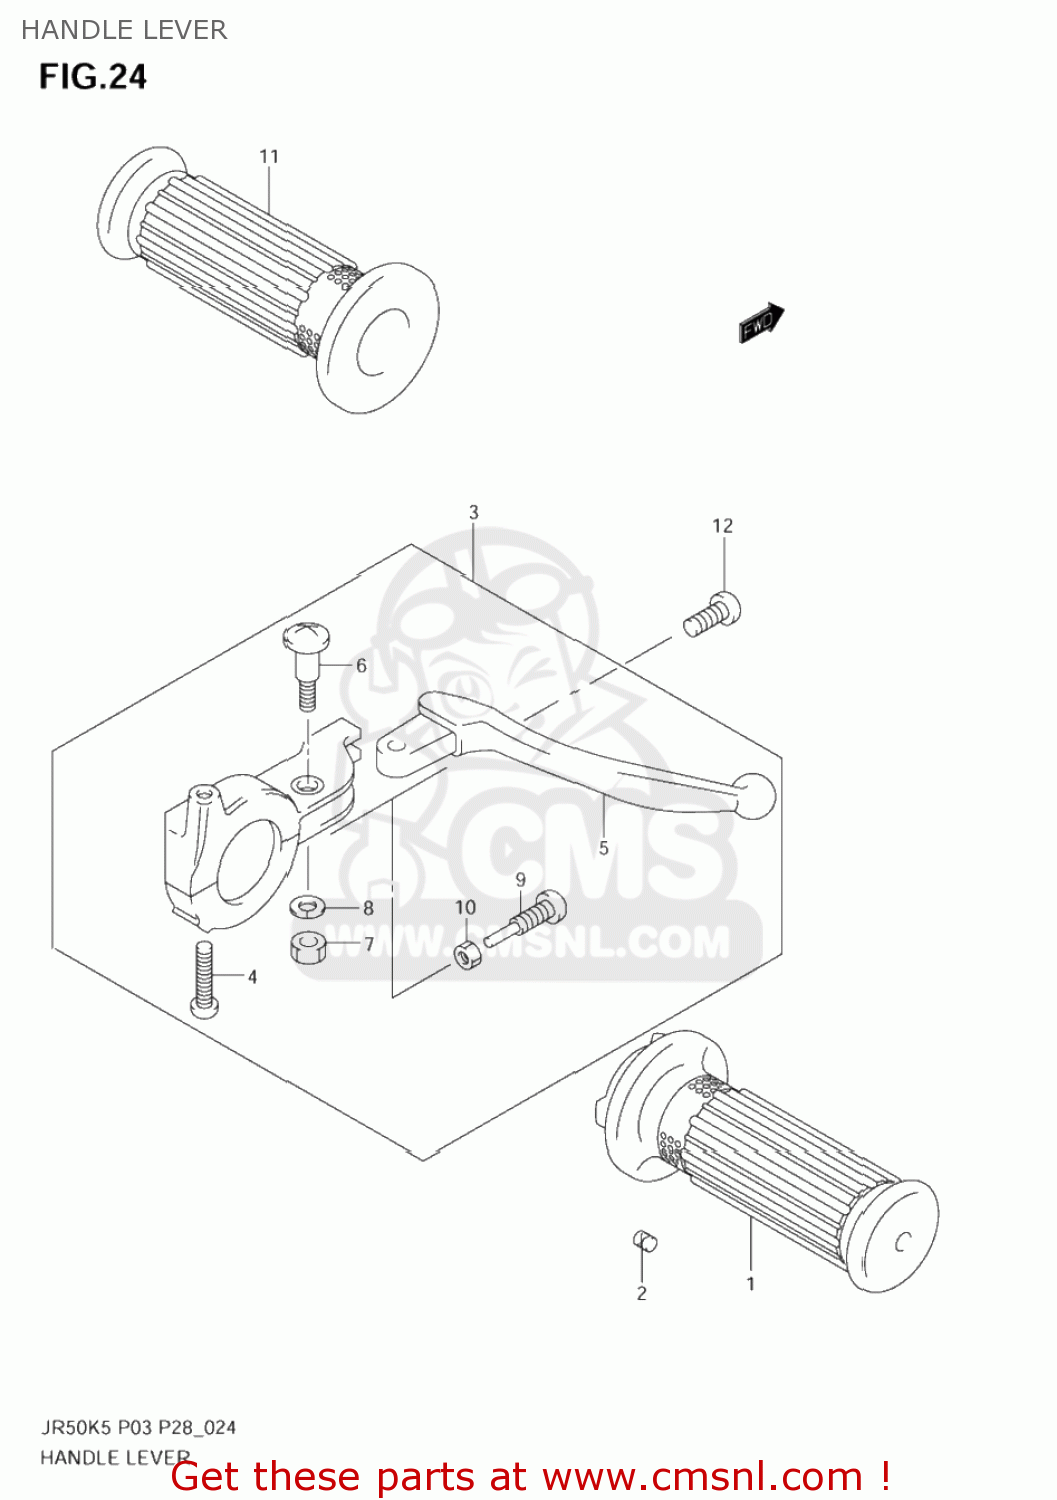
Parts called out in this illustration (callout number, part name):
1	GRIP,THROTTLE
2	PIECE,THROTTLE END
3	LEVER ASSY,BRAKE
4	SCREW(5X22)
5	LEVER,BRAKE
6	SCREW(5X20)
7	NUT
8	LOCK,WASHER
9	SCREW,THROTTLE GRIP ADJUST
10	NUT
11	GRIP,L
12	SCREW (M5X6)
